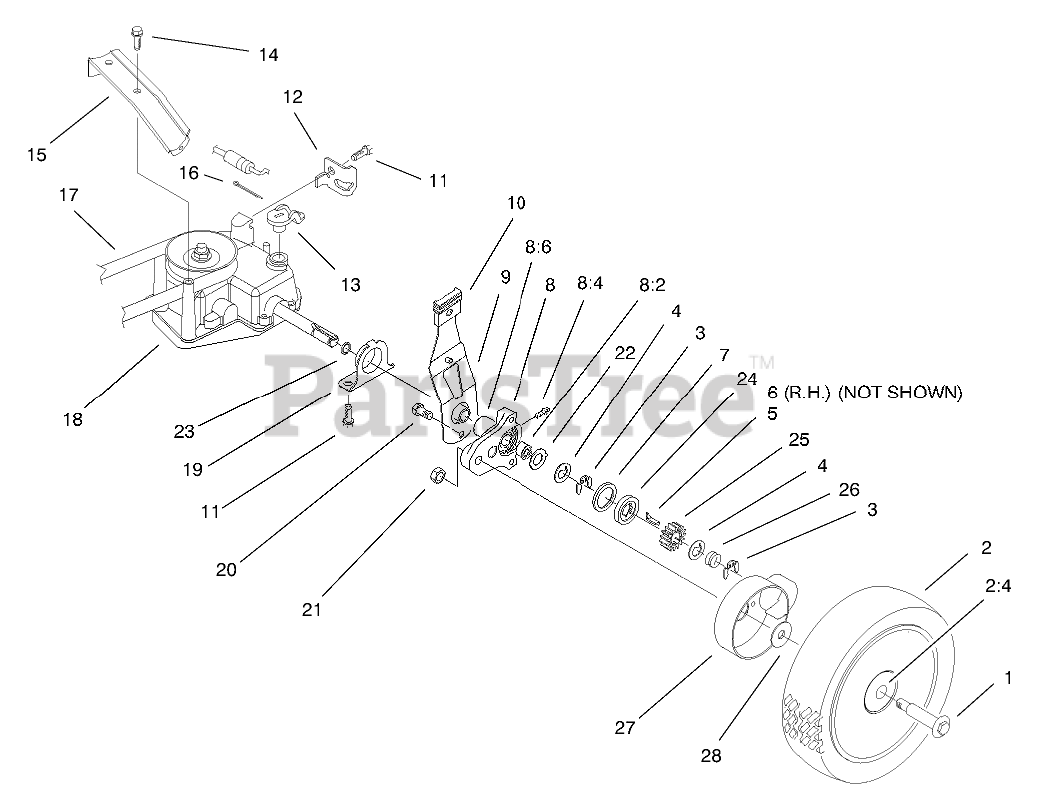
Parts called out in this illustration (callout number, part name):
1	BOLT-SHOULDER
2	WHEEL ASM
2:4	BUSHING
3	RING-CLIP, LOCKING
4	WASHER-THRUST, KEYED
5	KEY-ROCKING, LH
6	KEY-ROCKING, RH
7	RING-FRICTION
8	PIVOT ARM ASM
8:2	BEARING-ROLLER
8:4	FITTING-GREASE
8:6	BUSHING
9	SPRING ARM ASM
10	KNOB-ARM
11	SCREW-HWHTF
12	RETAINER-CABLE
13	LEVER-SHIFT
14	SCREW-HWHTF
15	Bracket-BeltGuide
16	PIN-COTTER
17	V-BELT
18	GEARCASE ASM
19	CAP-END
20	SCREW-HSH, THREAD FORMING
22	WASHER-ARM, PIVOT
23	O-RING
24	WASHER-CLUTCH
25	GEAR-PINION
26	SPRING-COMPRESSION
27	COVER-WHEEL
28	SPACER-COVER, WHEEL
